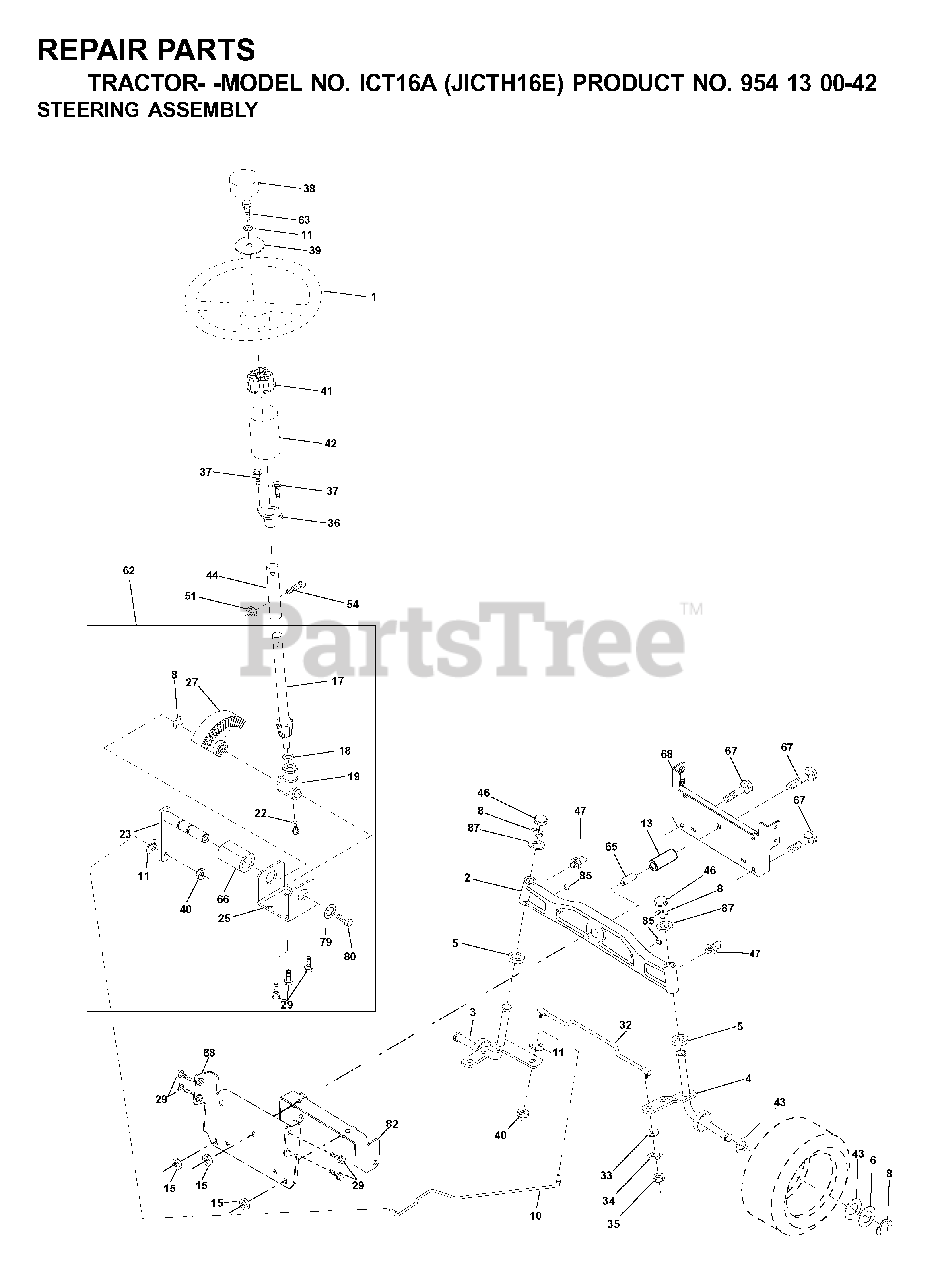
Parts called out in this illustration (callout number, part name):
2	AXLE
3	SPINDLE.ASM.LH.15"TIRES
4	SPINDLE.ASM.RH.15"TIRES
8	RING CLIP
10	DRAGLINK.15".TIRES
11	WASHER, LOCK 3/8
13	TUBE, PIVOT AXLE
15	NUT
17	SHAFT ASM STEERING
18	THRUST WASHER
19	STEERING SHAFT SUPPORT
22	SCREW.HX.WSH.HD
23	SHAFT ASSY PITTMAN
25	BRACKET STEERING
27	GEAR.SECTOR
29	SCREW 3/8-16X3/4
32	ROD.ASM.TIE.BALL.JOINT.NOVAN
33	WASHER M
34	LOCKWASHER
35	LOCKNUT
36	BUSHING, STEERING
39	WASHER 13/32 X 2-3/8 X 12 GA
40	GRIPCO NUT
41	STEERING WHEEL ADAPTOR
42	BOOT.STEERING.SHAFT.BLACK
44	EXT SHAFT STEERING
46	CAP.SPINDLE
47	ZERK M
51	NUT.71038.31-18.HEX.NYLOCK
54	BOLT.5/16-18X1-1/4 FULL.THREAD
62	STEERING KIT
65	SPACER BRACE AXLE
66	BEARING ARM
67	BOLT
68	BRACE.AXLE.15"TIRES
80	BOLT.HX.NYLON3/8-16X
82	BRACKET
85	FASTENER.XMAS.TREE
87	WASHER, FLAT .781 X 1 1/2"
